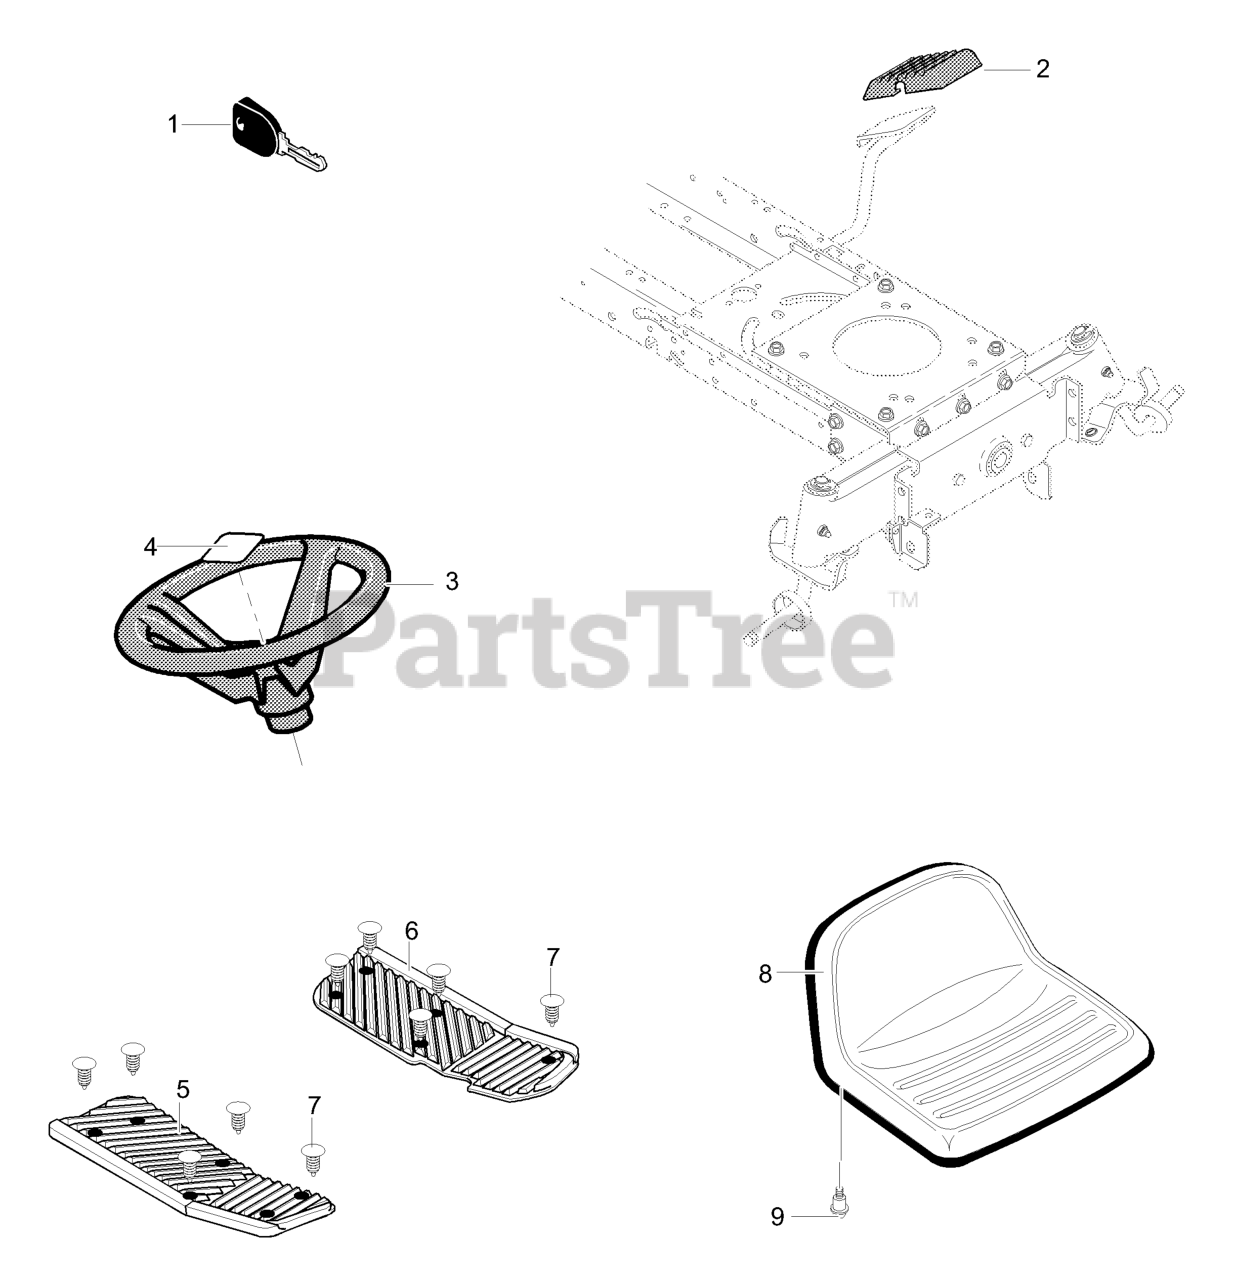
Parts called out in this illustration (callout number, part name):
1	Ignition Key
2	Pad, Clutch/Brake
3	Steering Wheel
4	Insert, 4-Spoke
5	Footrest Pad RH
6	Footrest Pad LH
7	Ratchet Fastener
9	Shoulder Bolt 5/16-18
